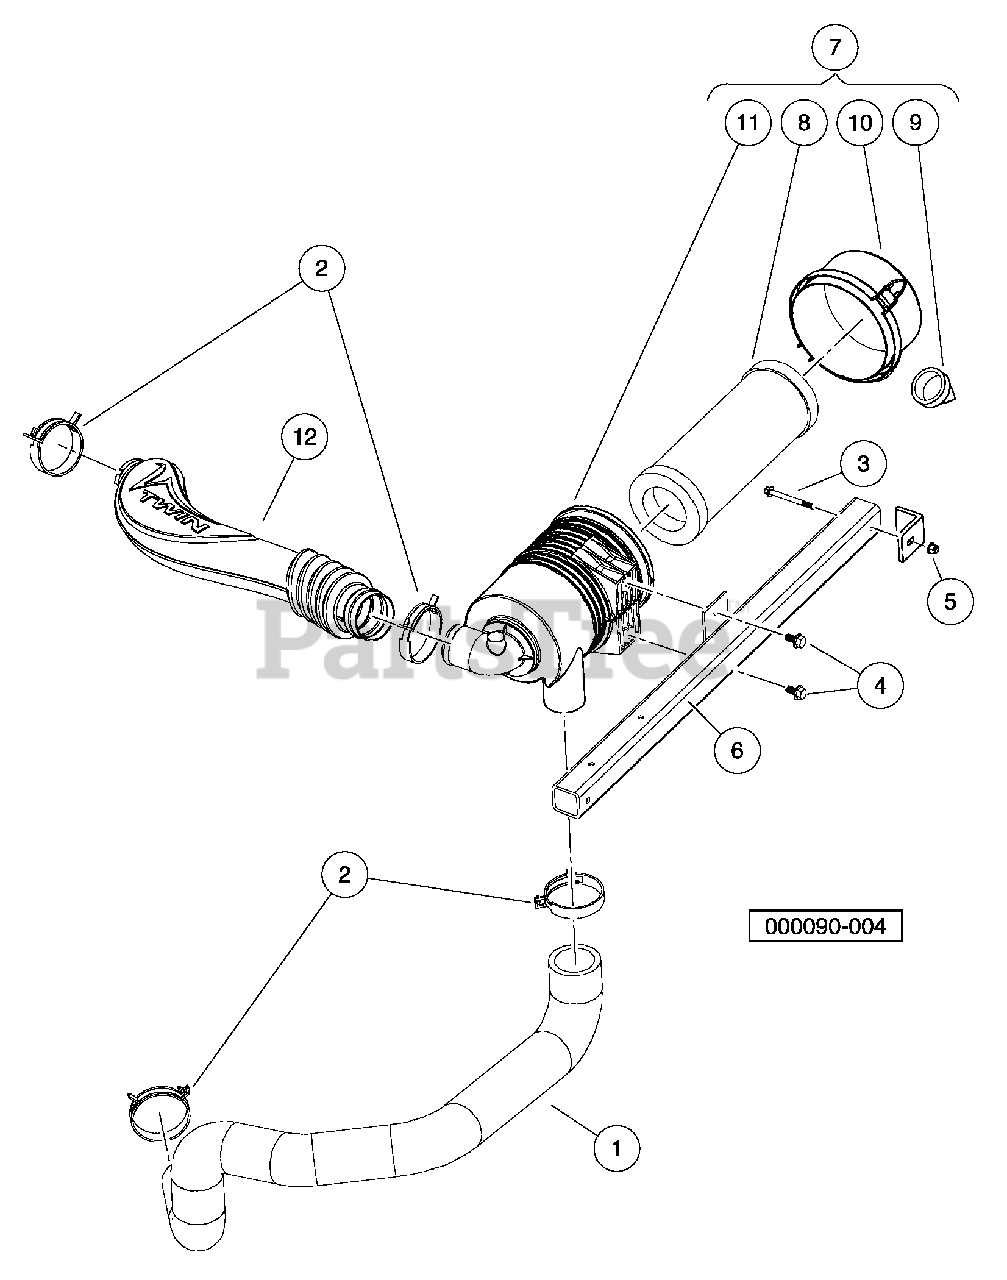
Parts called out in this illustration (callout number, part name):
1	Hose, Intake, Primary.
2	Clamp, Hose, Ctb 64mm.
3	Bolt, M 6 X 1.0 X 65 Hex, Flange, Head, Black
4	Bolt Flanged Head, M8 X1.25x 16 with Loctite
5	Nut Flg, M6 X 1.0 Nylon.
6	Weldment, Support, Air Cleaner
7	Filter, Air, Canister, W/labe
8	Element, Filter, Air, 5 In.
9	Valve, Evacuator, Filter Air.
10	Cap, Latch Lock, Filter, Air.
11	Body, Canister, Filter, Air.
12	Hose, Intake, Fh680d.
